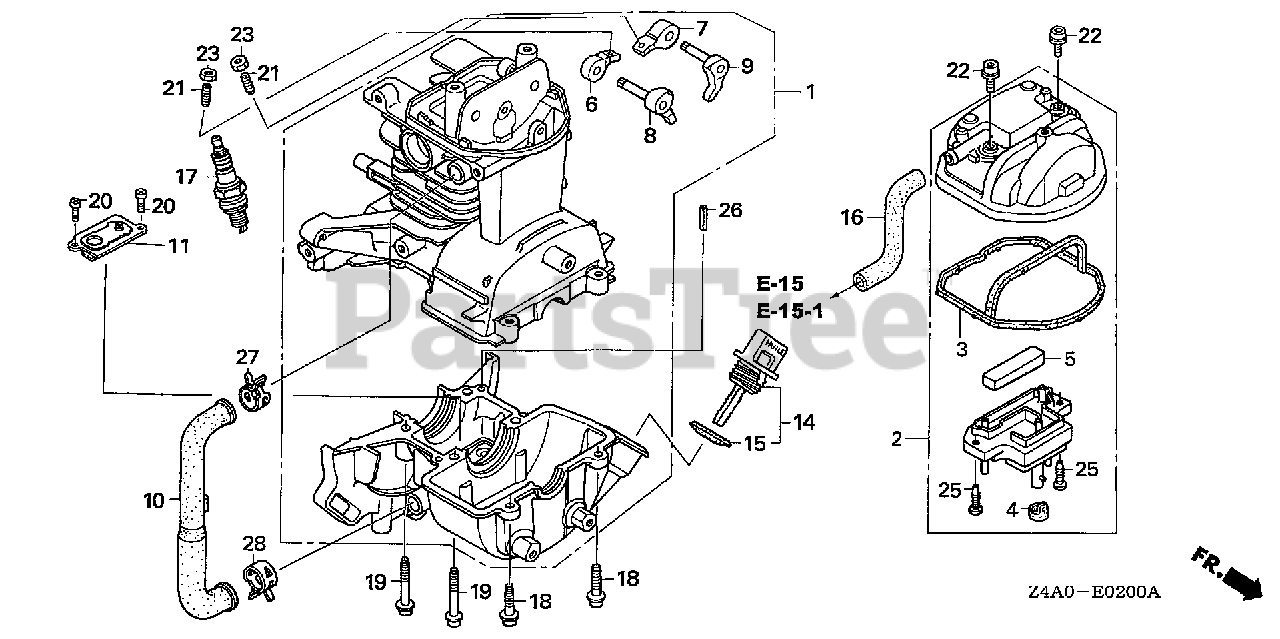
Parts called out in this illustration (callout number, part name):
1	CRANKCASE SET
2	COVER, CYLINDER HEAD
3	SEAL, HEAD COVER
4	GROMMET, HEAD COVER
5	FILTER, BREATHER
6	ARM, IN. VALVE ROCKER
7	ARM, EX. VALVE ROCKER
8	LIFTER, IN. VALVE
9	LIFTER, EX. VALVE
11	PLATE ASSY., OIL OUTLET VALVE
14	CAP ASSY., OIL FILLER
15	GASKET, OIL FILLER CAP
16	TUBE, BREATHER
17	SPARK PLUG (CMR4H) (NGK)
17	SPARK PLUG (CMR5H) (NGK)
17	SPARK PLUG (CMR6H) (NGK)
18	BOLT, SOCKET (5X20)
19	BOLT, SOCKET (5X30)
20	SCREW, PAN (4X8)
21	SCREW, TAPPET ADJUSTING
22	BOLT, SOCKET (5X12)
23	NUT, TAPPET ADJUSTING
25	SCREW, TAPPING (4X12)
26	PIN, SPRING (4X10)
27	CLAMP, TUBE (D12)
28	CLAMP, TUBE (D13)
